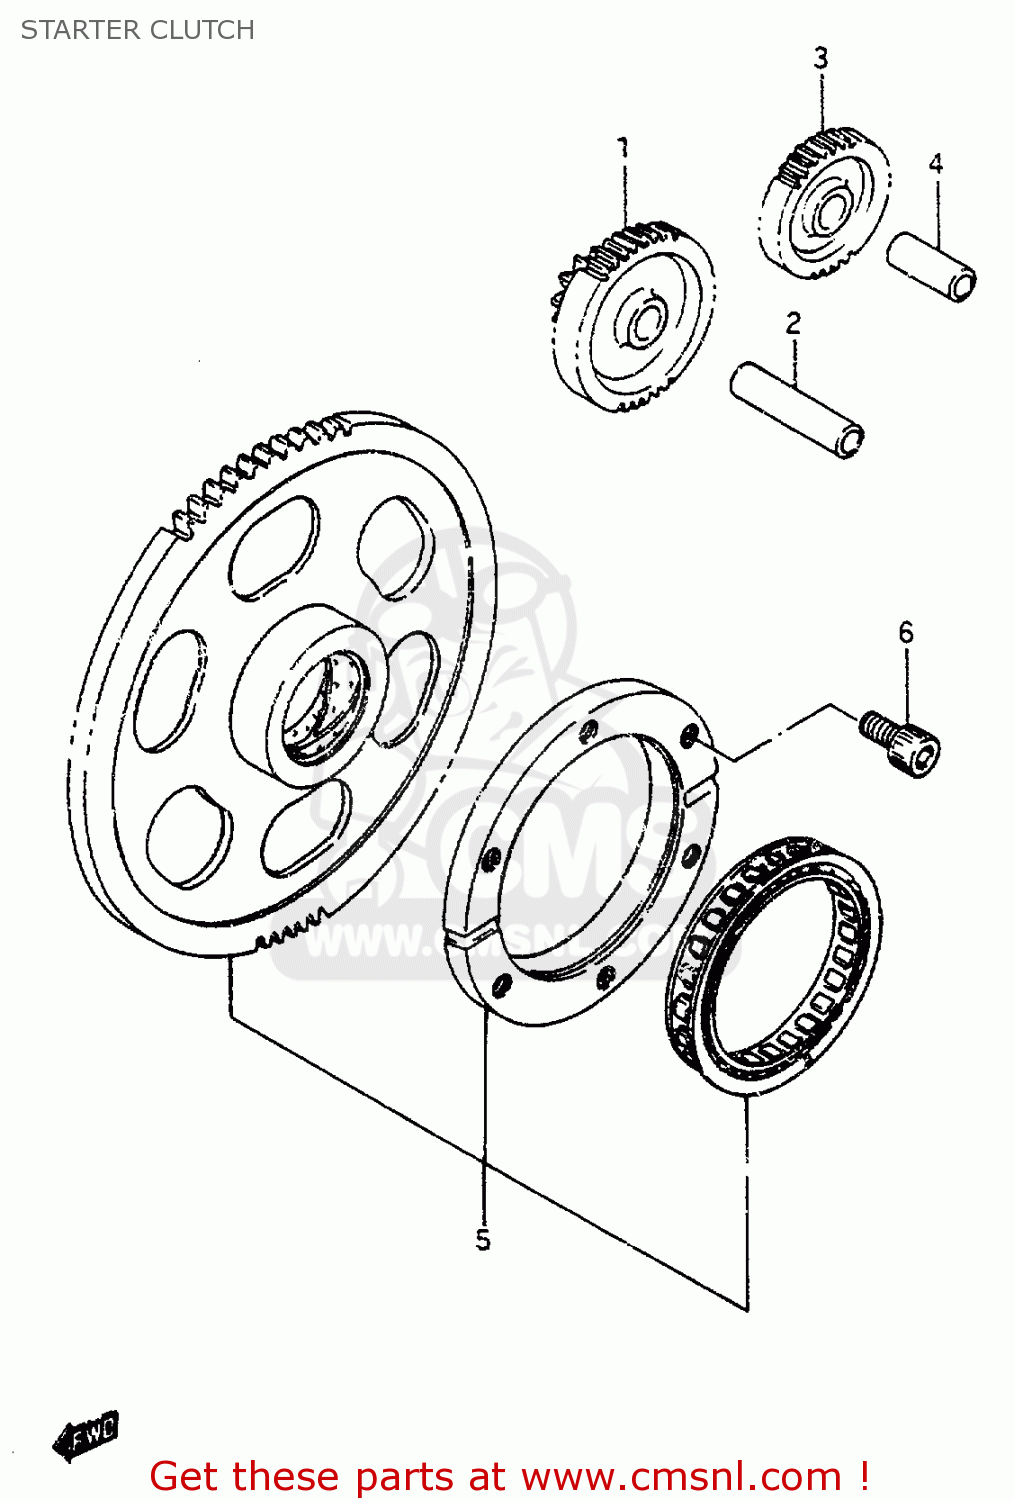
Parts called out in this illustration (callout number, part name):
1	GEAR,STARTER IDLE NO.1
2	PIN,10X43
3	GEAR,STARTER IDLE NO.2
4	PIN
5	CLUTCH SET,STARTER
6	BOLT
